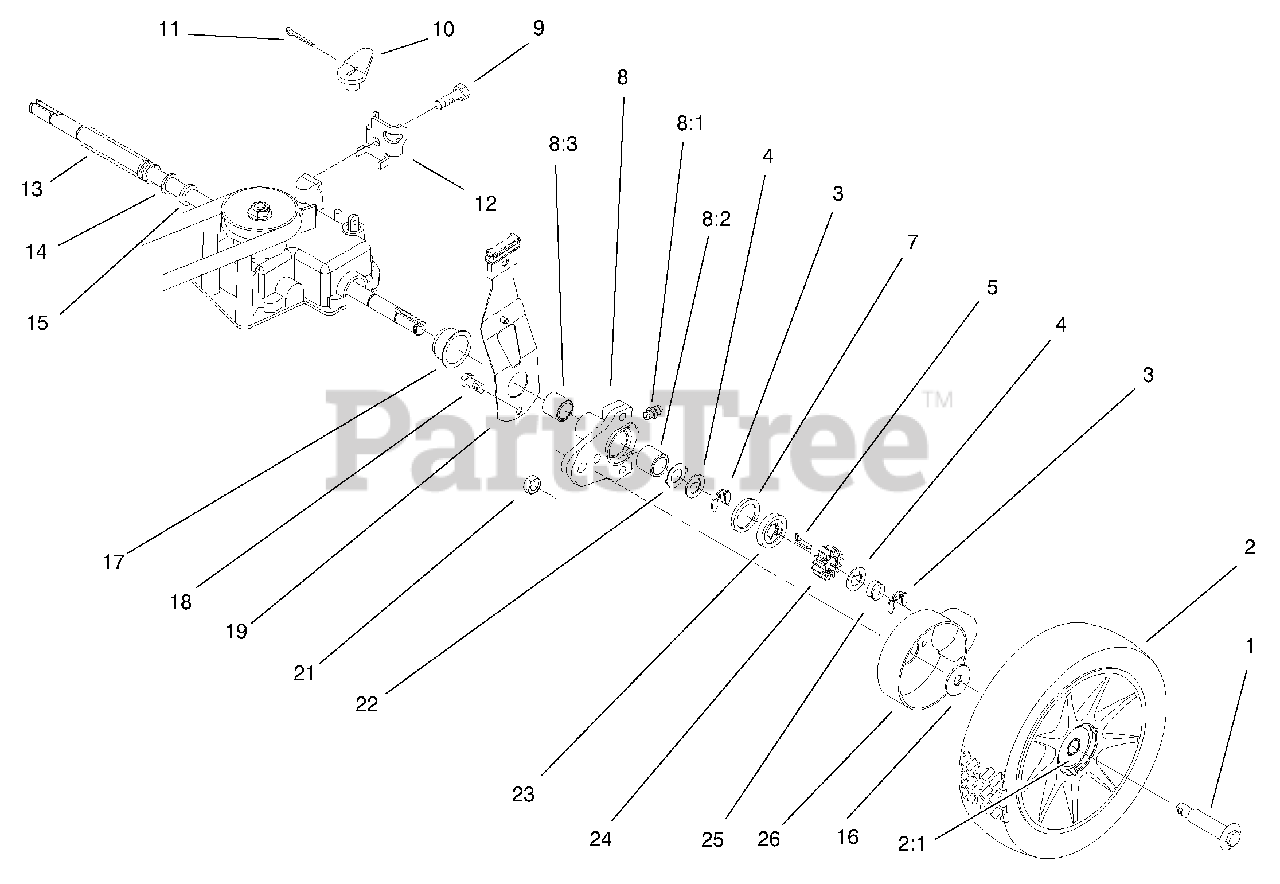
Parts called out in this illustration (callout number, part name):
1	Bolt-Shoulder
2	Wheel & Tire ASM
3	Ring-Klip
4	Washer-Thrust, Keyed
5	Key-Rocking, LH
7	Ring-Friction
8	Arm ASM-Rear Height Adjustment
8:1	Fitting-Zerk
10	Lever-Shift
11	Pin-Cotter
12	Clamp-Cable
13	Cover-Shaft, Drive
16	Washer-Stepped
17	Ring-Isolator
19	Rear Spring Arm ASM-LH
22	Washer-Arm, Pivot
23	Washer-Clutch
24	Gear-Pinion
25	Spring-Compression
26	Cover-Wheel
